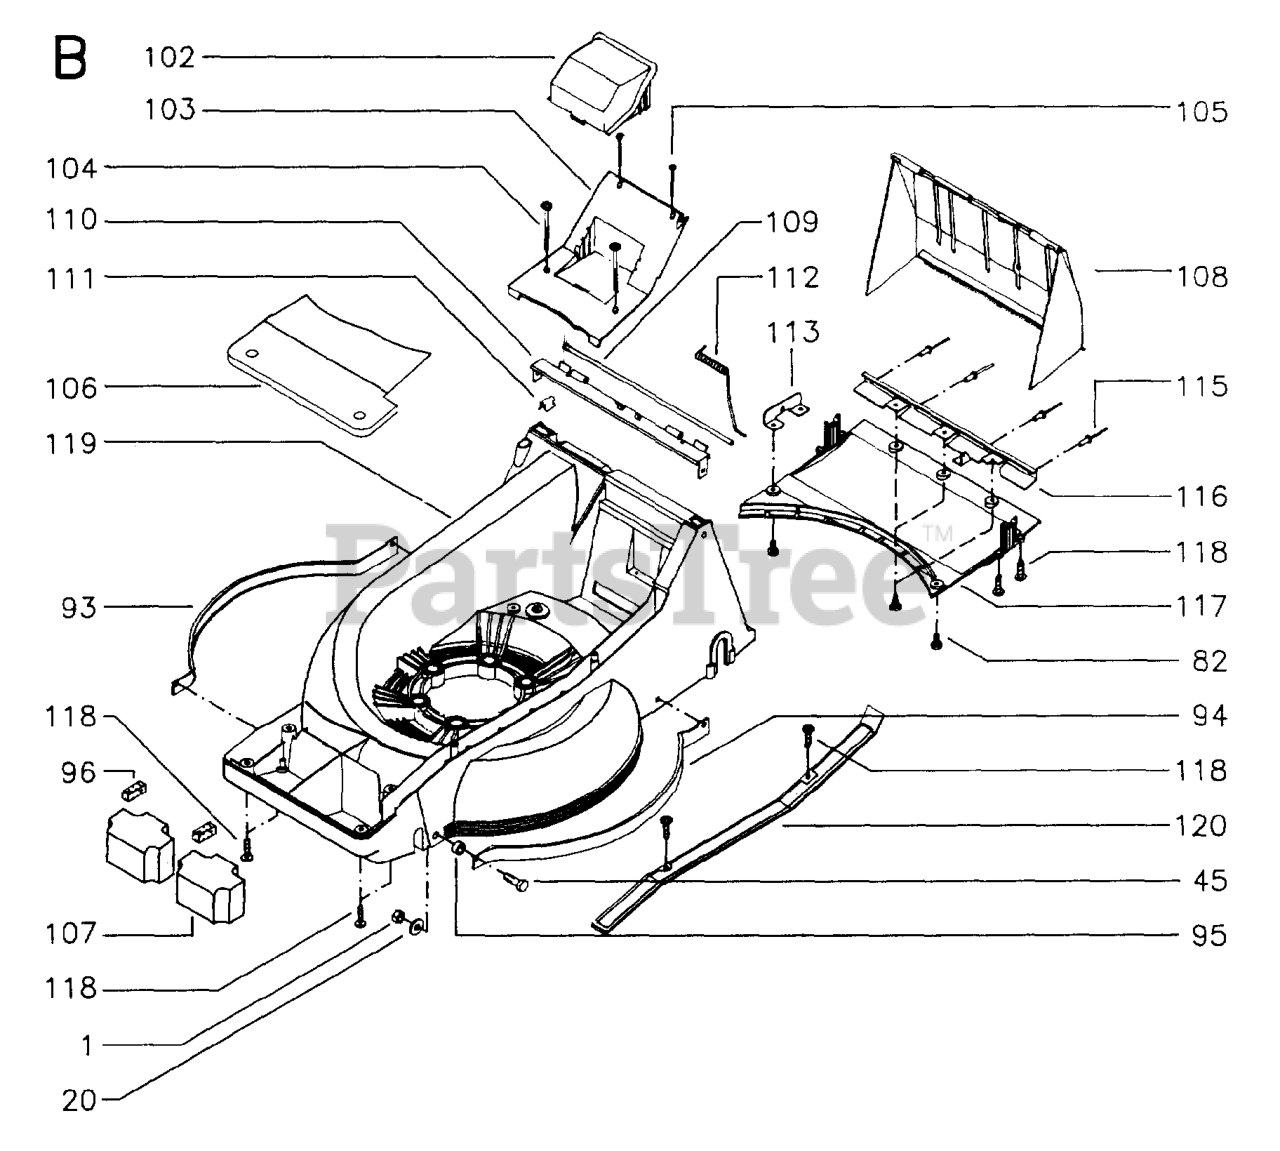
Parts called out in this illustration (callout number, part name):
1	LOCKNUT M8
45	SCREW M6S 8X25
93	DECK PROTECTOR RH
94	DECK PROTECTOR LH
106	DECK FRONT COVER
107	COUNTERWEIGHT
110	BRACKET
113	BRACKET
120	COVER
